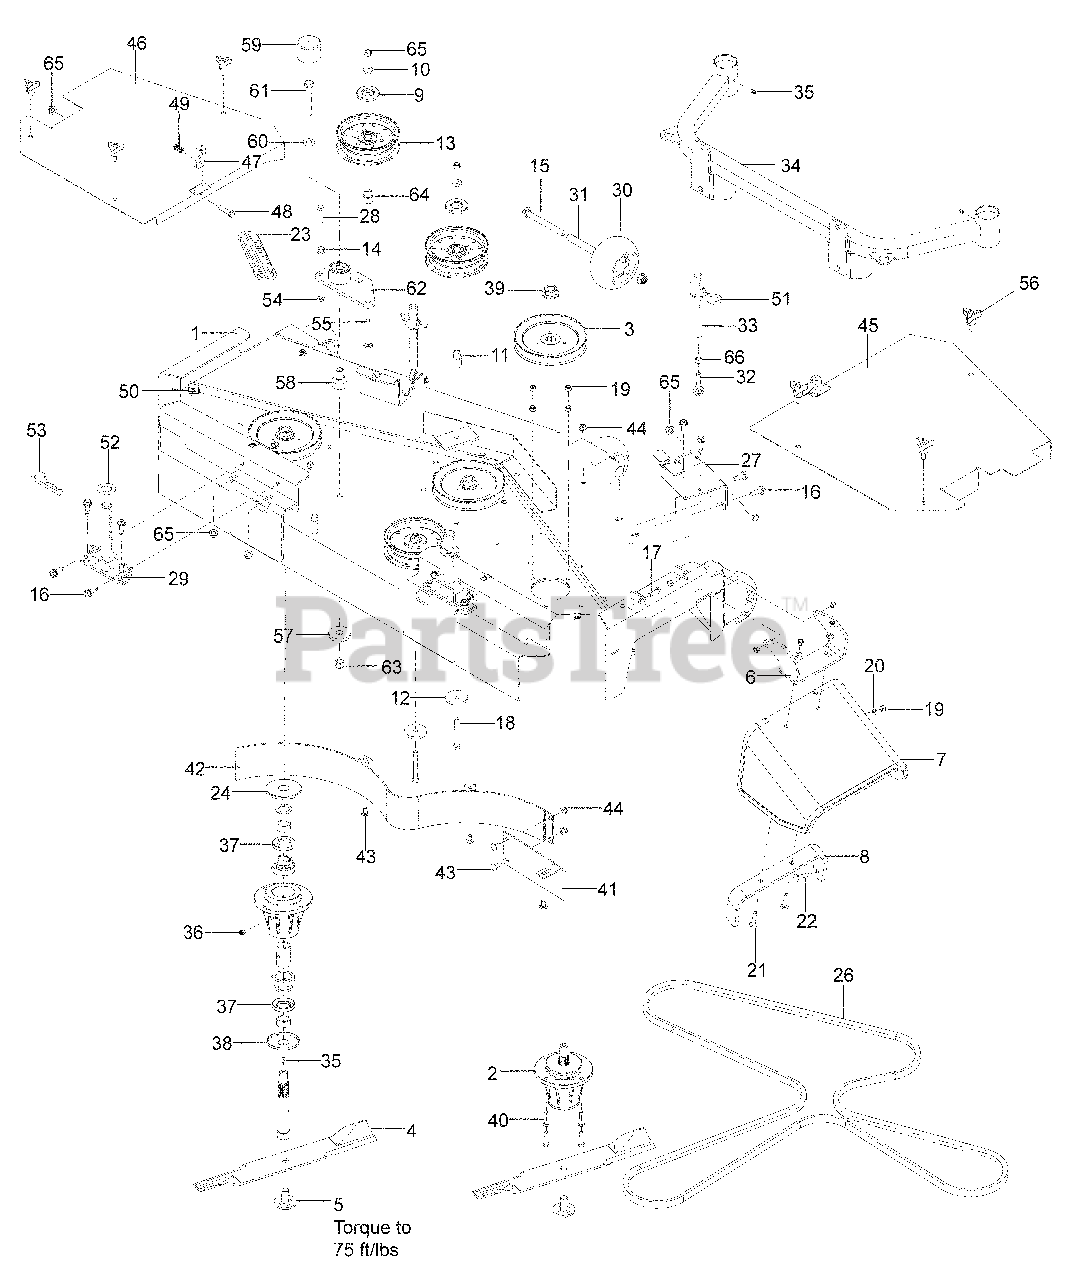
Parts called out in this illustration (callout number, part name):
1	CUTTER DECK w/DECALS
2	HOUSING ASM
4	BLADE, 21"
5	BLADE BOLT
6	HINGE, CHUTE
7	CHUTE, RUBBER
8	REINFORCEMENT, BRCKT
9	SHIELD, DUST
10	WASHER 3/8 THICK
11	BUSHING, IDLER
12	WASHER, HEAVY
13	PULLEY, IDLER
14	NUT 3/8-16 HEX WHIZLK
15	RHSNB ½-13 x 4¾
16	BOLT 3/8-16 x 1 THD FRM
17	HCS 5/16-18 x 1
18	HCS 3/8-16 x 3
19	NUT 5/16-18 HEX NYLOC
20	WASHER 5/16 SAE FLAT
21	RHSNB 5/16-18 x 1½
22	RHSNB 5/16-18 x 1¼
24	DUST CAP, TOP
25	WASHER 3/8 SPECIAL
26	BELT, DECK
27	SUPPORT, FRONT, RH
28	HCS 3/8-16 x 1½ GR 8
29	PIN ASSEMBLY
30	ROLLER, GAUGE
31	TUBE, AXLE
32	ROD END, RH
34	SUPPORT, CASTER
36	POPPET, GREASE
37	SHAFT SEAL
38	DUST CAP, BOTTOM
39	NUT ¾-16 FLANGE
40	HCS 5/16-18 x 1¼
41	BAFFLE, CENTER
42	BAFFLE, MAIN
43	RHSNB 5/16-18 x 5/8
44	NUT 5/16-18 HEX FLG NYLOC
48	HCS 3/8-16 x 1½
49	SPRING, COMPRESSION
50	RETAINER, U TYPE
51	WASHER ¾ FLAT SAE
53	HAIR PIN COTTER
54	NUT 3/8-16 HEX JAM
55	RHSNB 3/8-16 x 2¾
56	KNOB
57	WASHER, SUPPORT
58	PIVOT, BEARING
59	CAP, VINYL
60	WASHER ½" BELLEVILLE
61	HCS ½-13 x 3¼
62	ARM, IDLER w/ BEARINGS
63	NUT ½ HEX NYLOC
64	BUSHING, IDLER
65	NUT 3/8-16 HEX FLG
66	NUT 3/8-24 HEX GR 2
